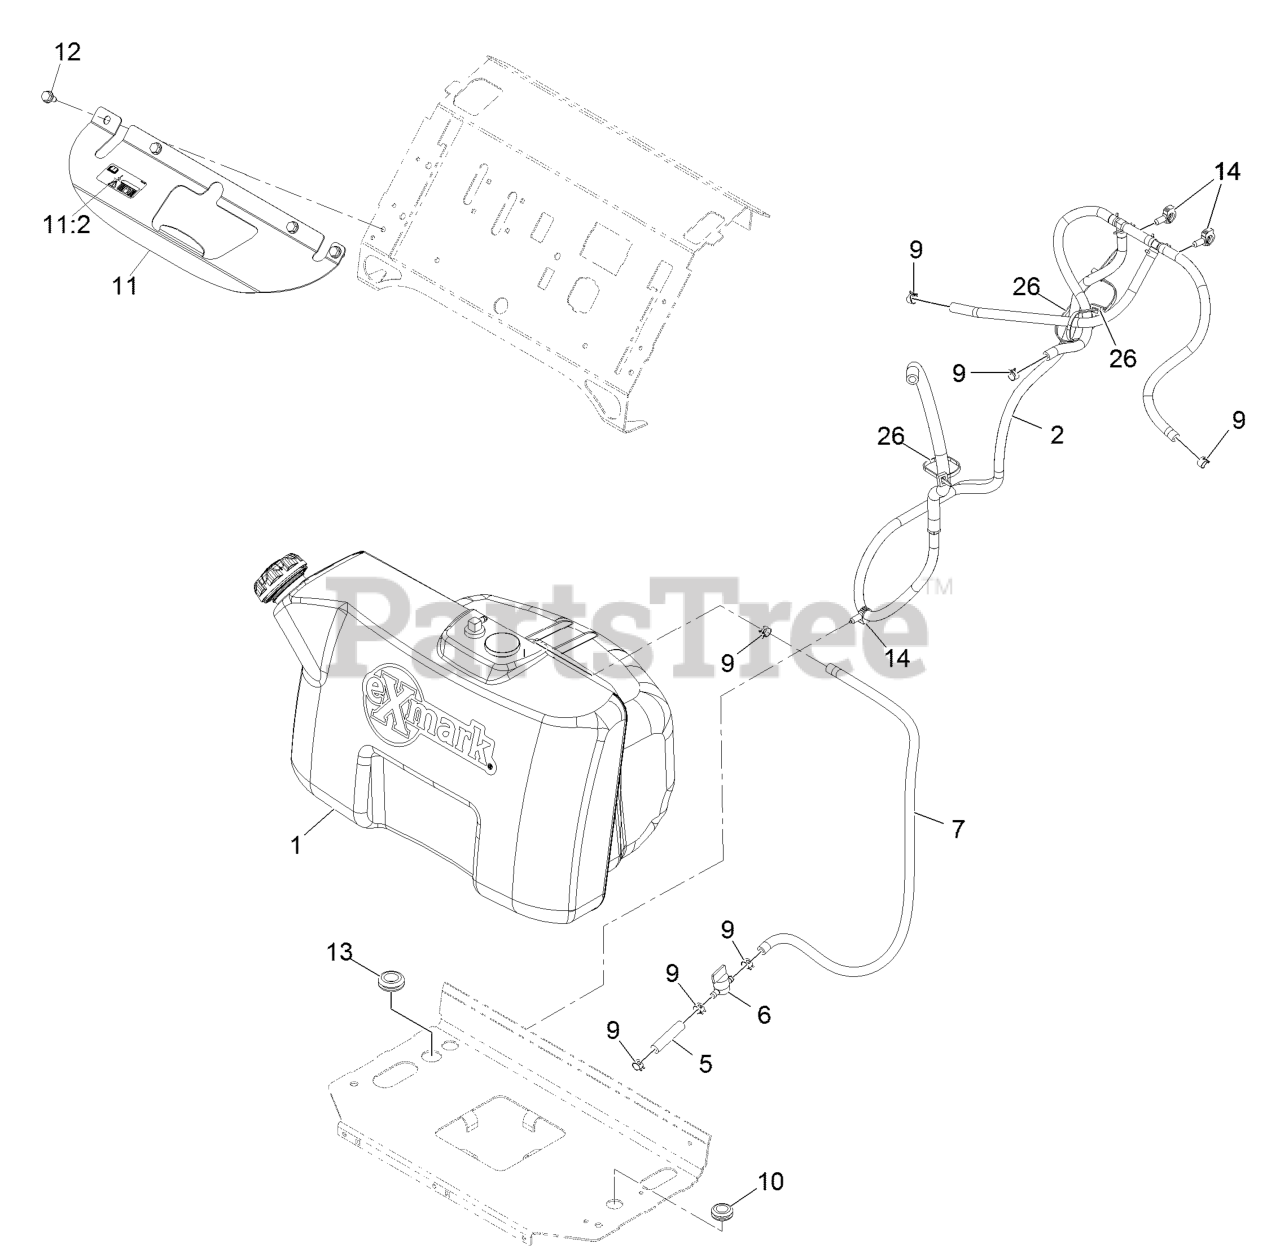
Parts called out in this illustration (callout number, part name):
2	VENT ASM
5	HOSE-FUEL
6	VALVE-FUEL
7	HOSE-FUEL
9	CLAMP-HOSE
10	GROMMET
11	BRACKET-TANK
11:2	Decal-Fill, Fuel
12	Screw-HWH 5/16-18 X 3/4 Tf
13	GROMMET
14	CLIP-HARNESS
26	TIE-CABLE
